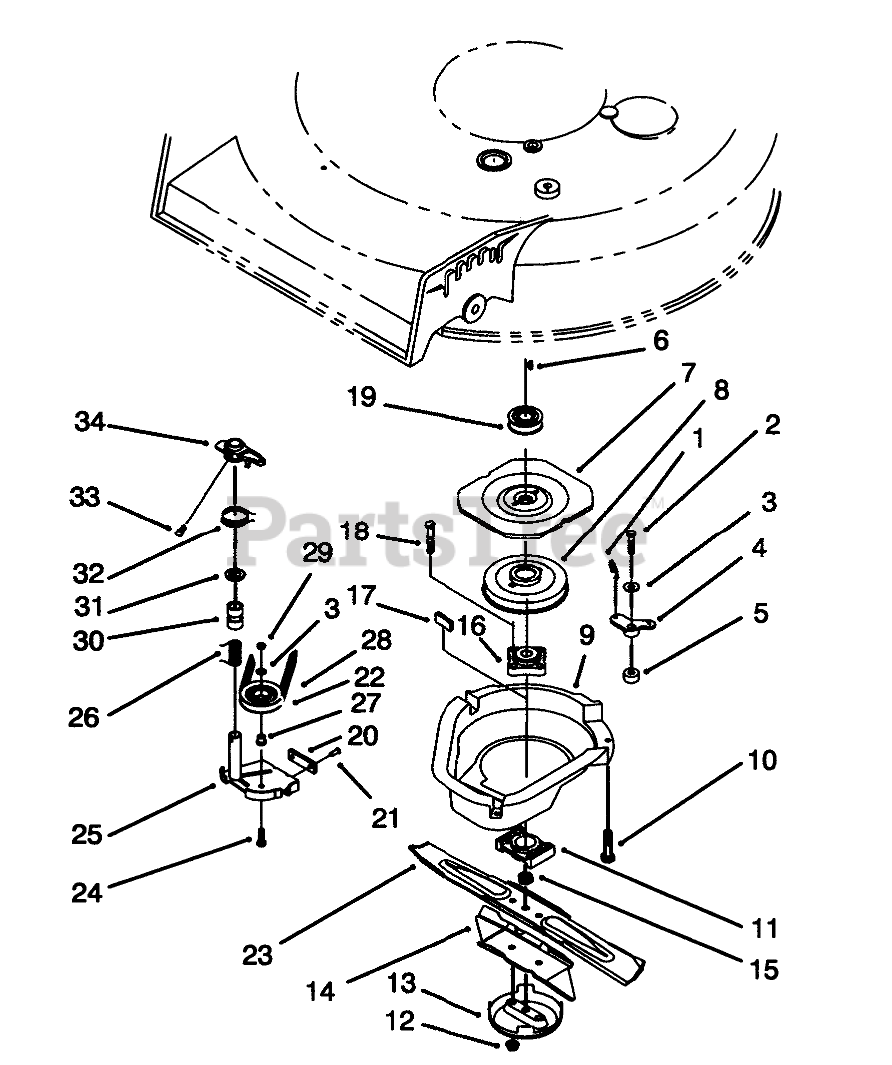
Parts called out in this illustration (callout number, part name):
1	LINK-CONTROL
2	Capscrew
3	WASHER-PLAIN
4	BELLCRANK
5	SLEEVE-BELLCRANK
6	KEY-WOODRUFF
7	Flywheel
8	Drum-Brake
9	SHIELD BBC
10	SCREW-HWH
11	SPACER-BLADE
12	NUT-LOCK
13	CUP-SCALP, ANTI
14	Accelerator
15	NUT-LOCK, NI
16	HUB ASM
17	DAMPENER-VIBRATION
18	BOLT-BLADE
19	PULLEY
20	Pad-Brake
21	.185 DIA X .375 RT +
22	PULLEY-IDLER
23	Blade
24	SCREW-HH
25	Brake Plate (Incl. Ref. #20 & 21)
26	SPRING-TORSION
27	HUB-PULLEY, IDLER
28	V-BELT
29	NUT-LOCK, NI
30	BEARING
31	WASHER
32	SPRING-TORSION
33	SCREW-HH
34	LEVER
